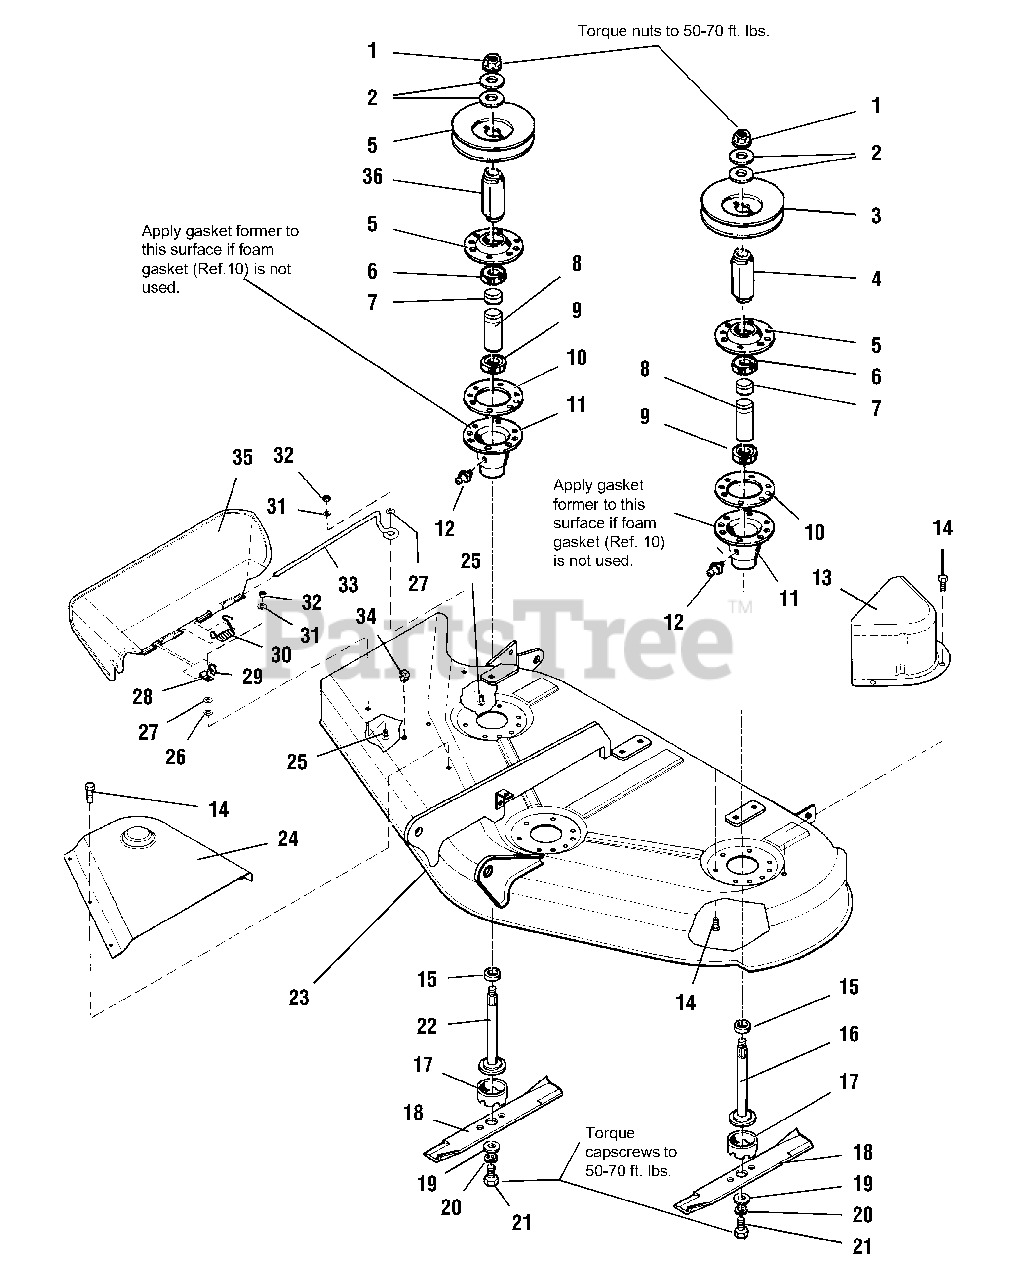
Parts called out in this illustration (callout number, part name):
1	NUT, Hex, Flange, 9/16-8
2	WASHER, Belleville
4	HUB, Adapter
5	COVER, Arbor Housing
10	GASKET, Foam
11	HOUSING ASSEMBLY, Arbor Bottom, w/Lube Fitting
12	FITTING, Grease
13	COVER, Arbor
14	SCREW, Hex, Taptite, 5/16-18 x 3/4
16	SHAFT, Arbor (LH)
17	SHIELD, Grass, Lower
18	BLADE, Mower, 16-1/8
19	WASHER, Hex
20	WASHER, Spring
21	CAPSCREW, Hex, Hd., 7/16-14 x 1
22	SHAFT, Arbor (Center & RH)
23	MOWER HOUSING ASSY., Mower (Orange)
23	MOWER HOUSING ASSY., Mower (Black)
24	COVER, Arbor
25	CARRIAGE BOLT, 1/4-20 x 7/8
26	NUT, Push On
27	WASHER, Plain
29	WASHER, Plain, 5/16
31	LOCKWASHER, 1/4
32	NUT, Hex, 1/4-20
33	ROD, Deflector, Front
35	DEFLECTOR, Plastic
36	HUB, Pulley
